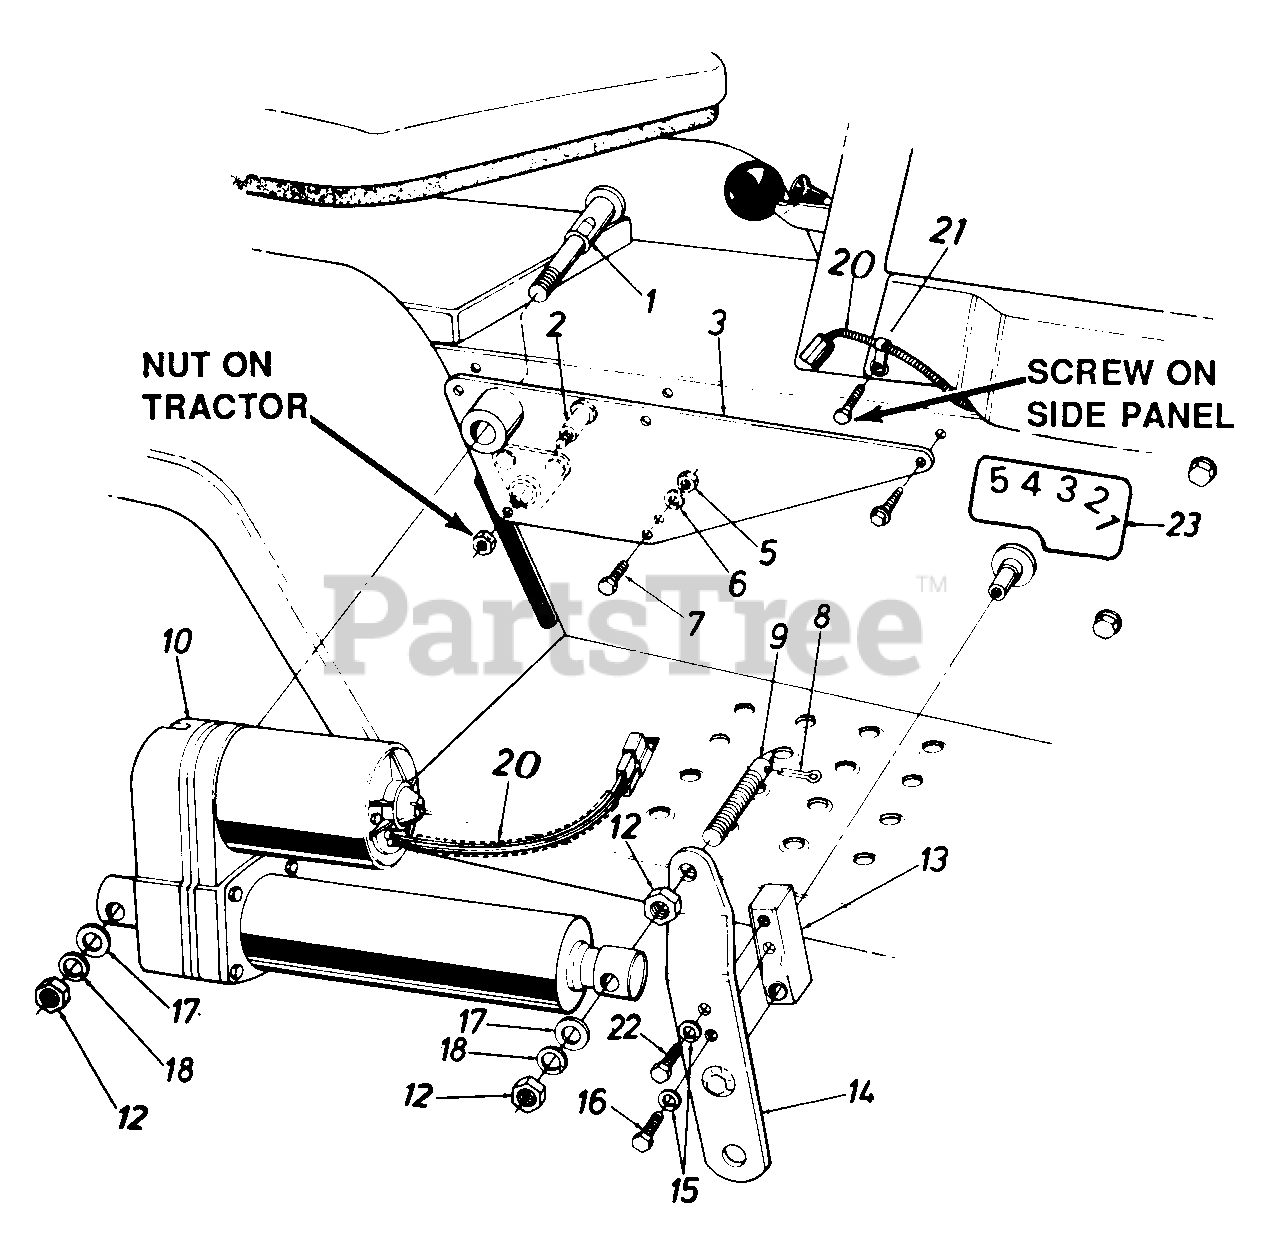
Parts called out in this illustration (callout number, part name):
1	Pivot Pin
2	Shld. Bolt .626 Dia. x .96"
5	Hex Nut 1/4"-28 Thd.
6	L-Wash. 1/4" I.D.
7	Hex Bolt 1/4-28 x .75" Lg. (Grade 5)
8	Cotter Pin
9	Indicator & Mtg. Pin
10	Electric Actuator
12	Hex Jam Nut 1/2-13 Thd.
13	Lift Shaft Drive
16	Hex Bolt 5/16-24 x 1.0 Lg. (Grade 5)
17	Fl-Wash. .53" I.D. x .93 O.D.
18	L-Wash. 1/2 I.D.
20	Plastic Harness
21	Clamp
22	Hex Bolt 5/16-18 x 1 Lg. (Gr.5)
23	Label
